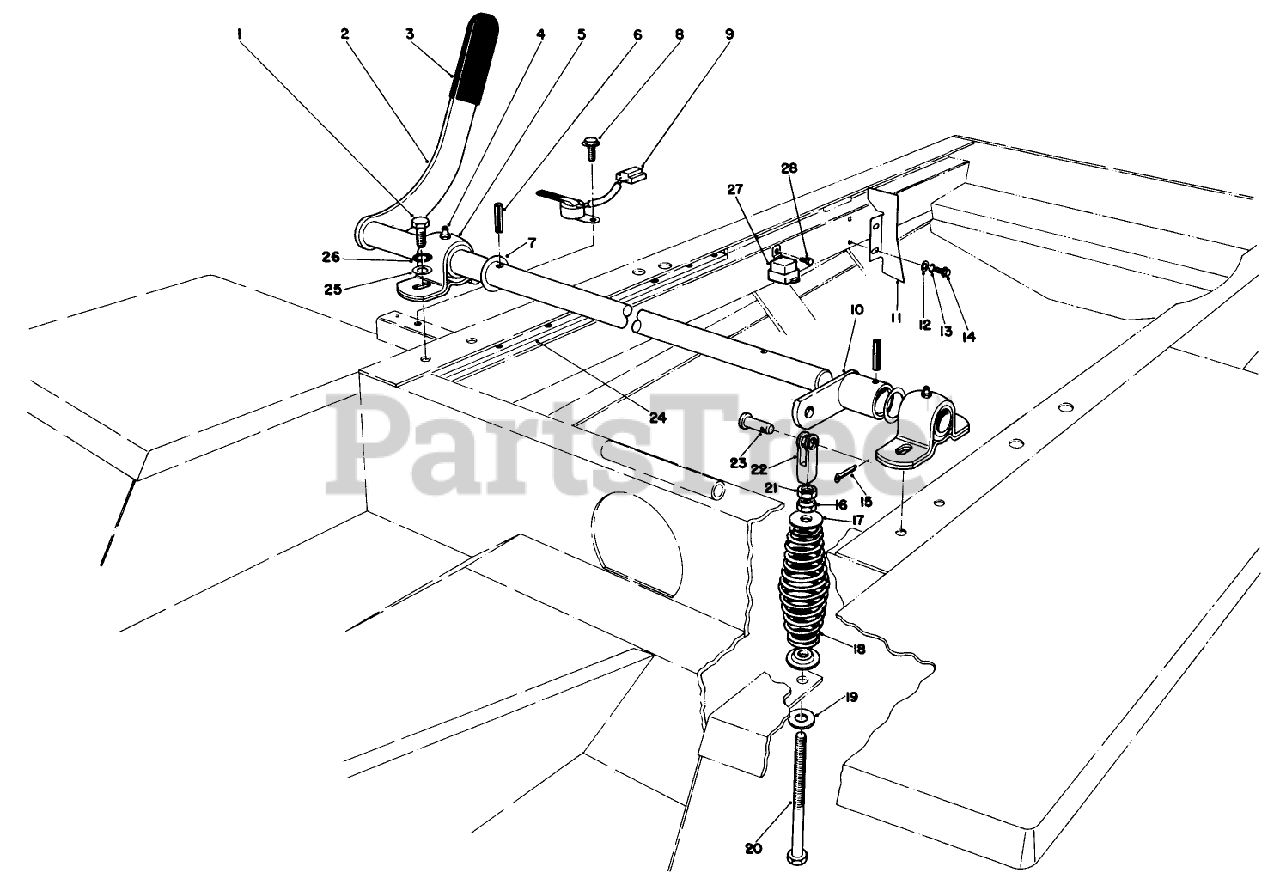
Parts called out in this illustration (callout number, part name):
1	SCREW-HH
2	P.T.0. Lever
3	GRIP-HANDLE
4	FITTING-GREASE
5	BEARING
6	PIN-SPRING
7	THRUST WASHER
8	SCREW-THD FRM,HWH
9	SWITCH ARM
10	Arm-Engagement
11	Shield-Heat
12	WASHER-PLAIN
13	WASHER-LOCK
14	SCREW-HWHTF
15	PIN-COTTER
16	NUT-HEX
17	SPRING RET TOP
18	COMP SPRING
19	WASHER
20	SCREW-ADJUSTING
21	NUT-HJ
22	Yoke
23	PIN-CLEVIS
24	Bar Frame Rail
25	WASHER-FLAT
26	WASHER-LOCK
27	RELAY
28	SCREW-HWH
